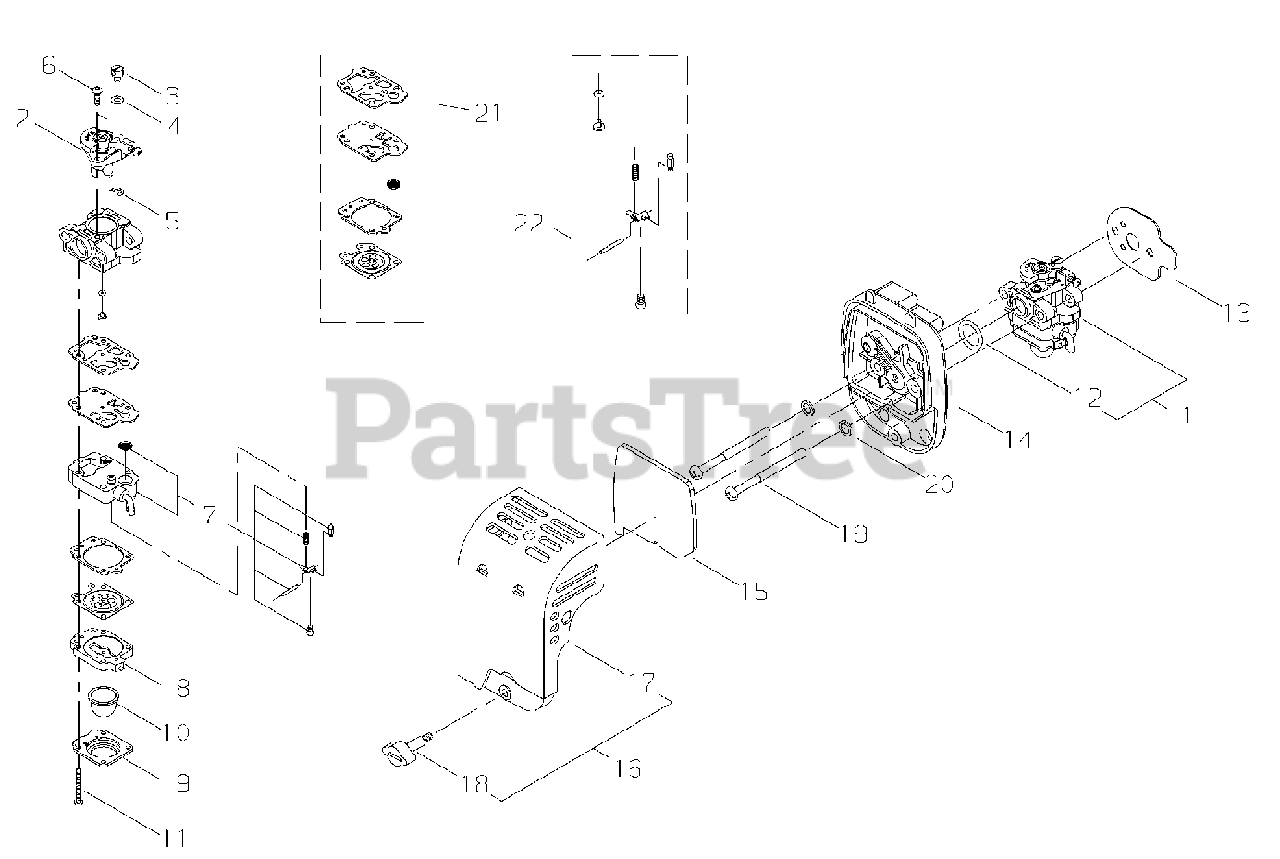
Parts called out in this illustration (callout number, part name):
2	THROTTLE VALVE SET
3	SWIVEL
4	WASHER
5	RING, RETAINING
6	SCREW
7	PUMP BODY ASSY
8	BASE, PURGE
9	COVER, PUMP
10	BULB, PURGE
11	SCREW, PUMP COVER
12	O-RING - 15
13	GASKET, INTAKE
14	AIR FILTER CASE ASSY
15	FILTER
16	CLEANER COVER ASSY
17	CLEANER COVER
18	THUMBSCREW
19	SCREW - 5X60
20	WASHER - 5
21	DIAPHRAGM/GASKET KIT
22	INLET NEEDLE VALVE KIT
